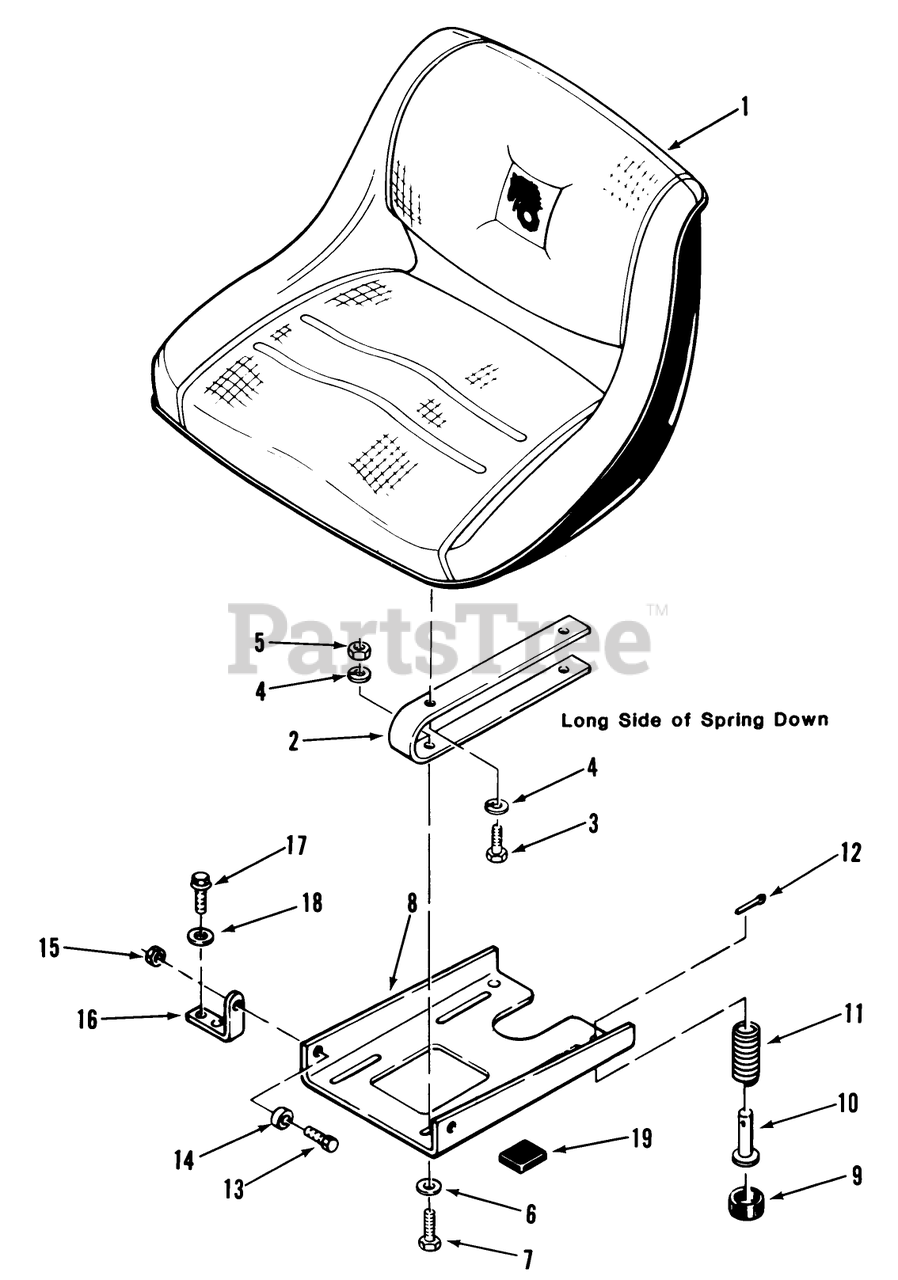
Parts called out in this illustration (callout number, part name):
6	WASHER 5/16 SAE
11	SPRING
14	BUSHING
18	WASHER 5/16 SAE
